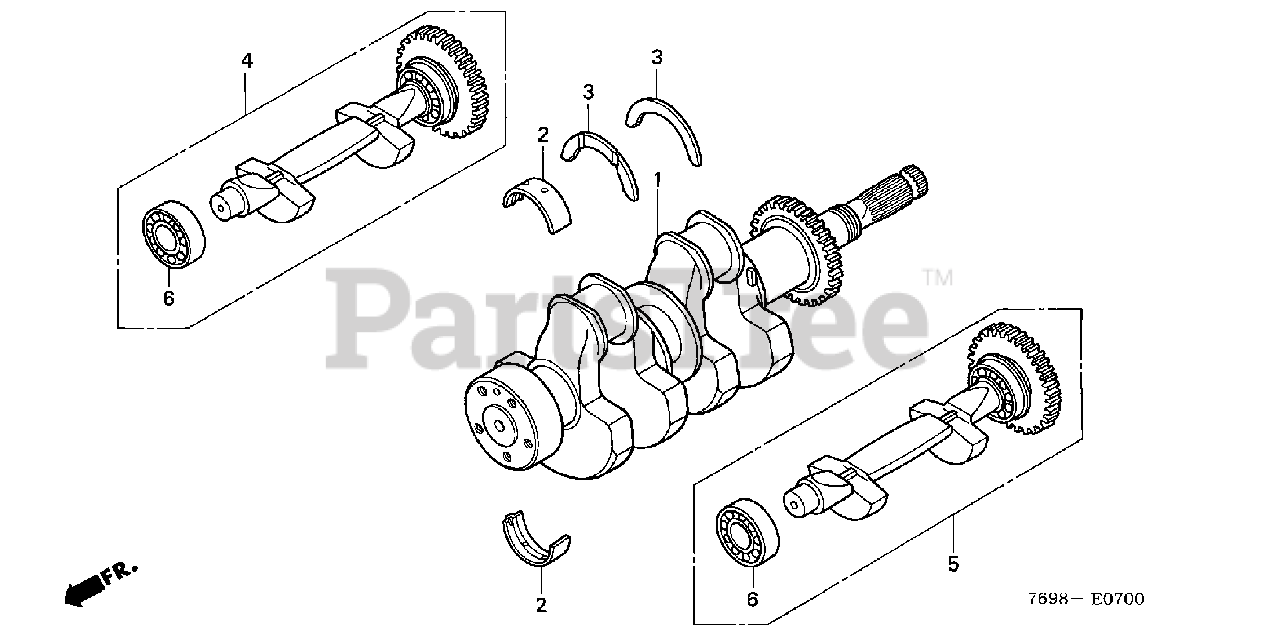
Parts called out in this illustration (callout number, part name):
1	CRANKSHAFT
2	BEARING A, MAIN (BLUE)
2	BEARING B, MAIN (BLACK)
2	BEARING C, MAIN (BROWN)
2	BEARING D, MAIN (GREEN)
2	BEARING E, MAIN (YELLOW)
2	BEARING F, MAIN (PINK)
2	BEARING G, MAIN (RED)
3	WASHER, THRUST
4	WEIGHT, R. BALANCER
5	WEIGHT, L. BALANCER
6	BEARING, RADIAL BALL (6203)
